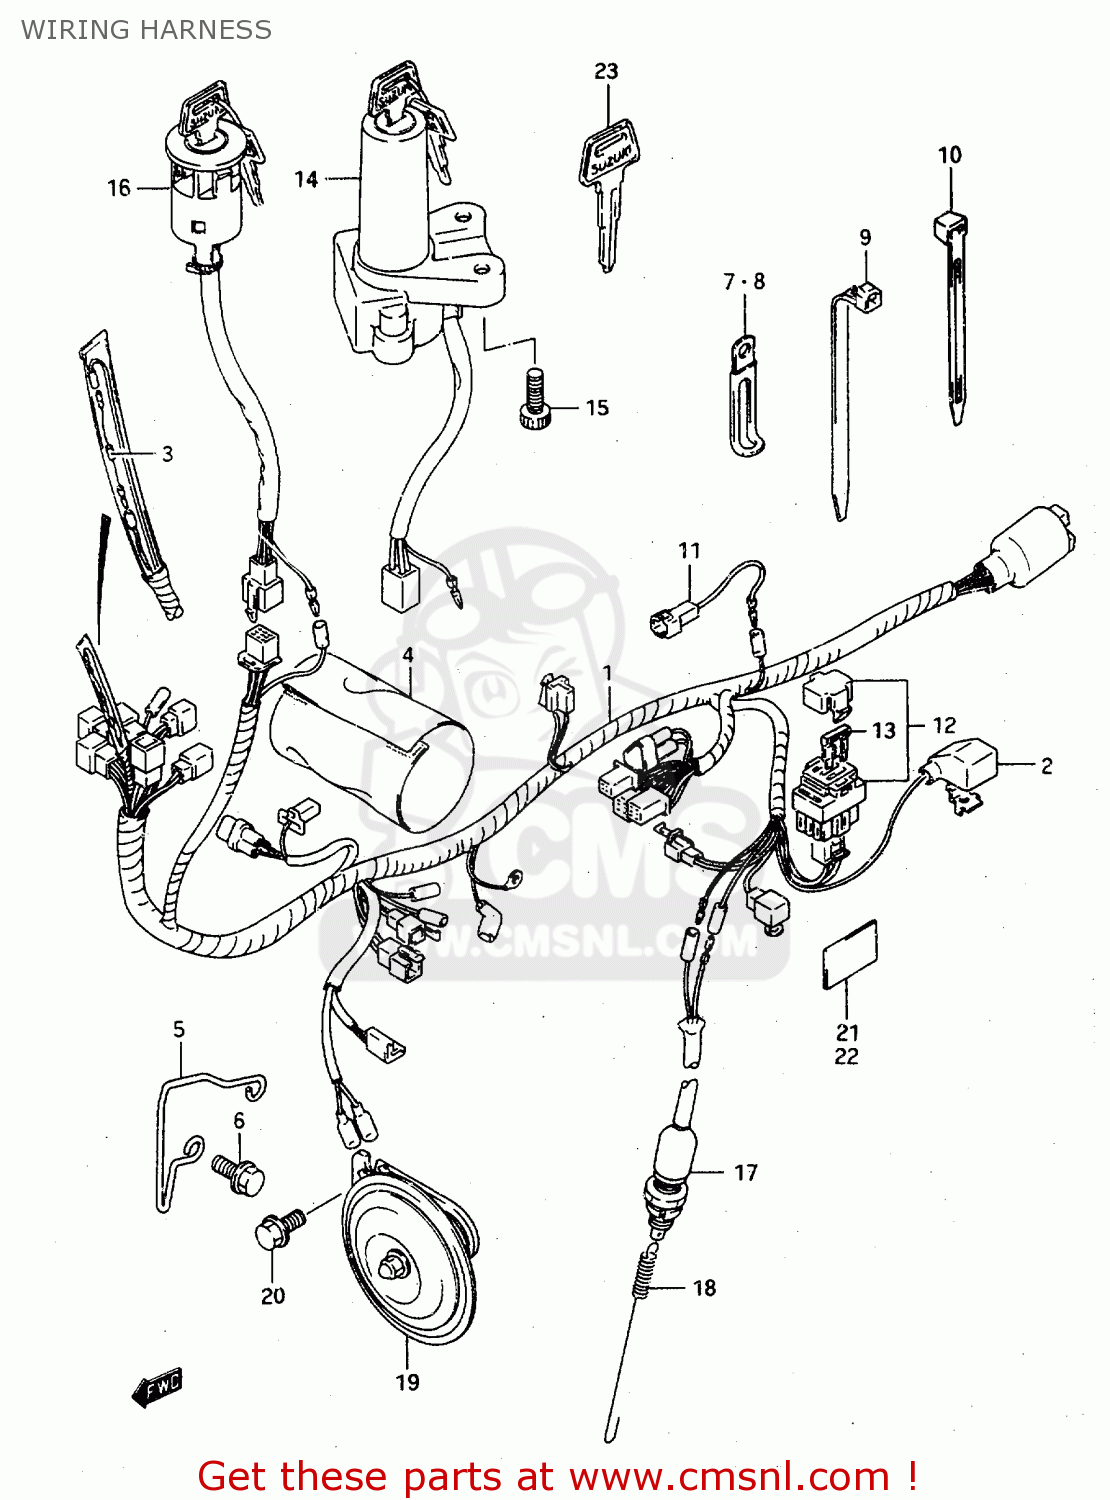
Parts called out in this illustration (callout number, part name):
1	HARNESS, WIRING
2	CAP,BATTERY PLUS TERMINAL
3	DIODE
4	COVER, HARNESS
5	GUIDE, WIRING HARNESS
6	BOLT
7	CLAMP
8	CLAMP
9	CLAMP(L:125)
10	CLAMP,L:88
11	WIRE, CDI LEAD
12	BOX ASSY,FUSE
13	FUSE(15A)
14	LOCK ASSY, STEERING
15	BOLT
16	SWITCH ASSEMBLY,IGNITION
17	SWITCH ASSY,STOP LAMP
18	SPRING
19	HORN ASSY
20	BOLT
21	PROTECTOR(30X60X3)
22	PROTECTOR(30X30X3)
23	KEY,BLANK
